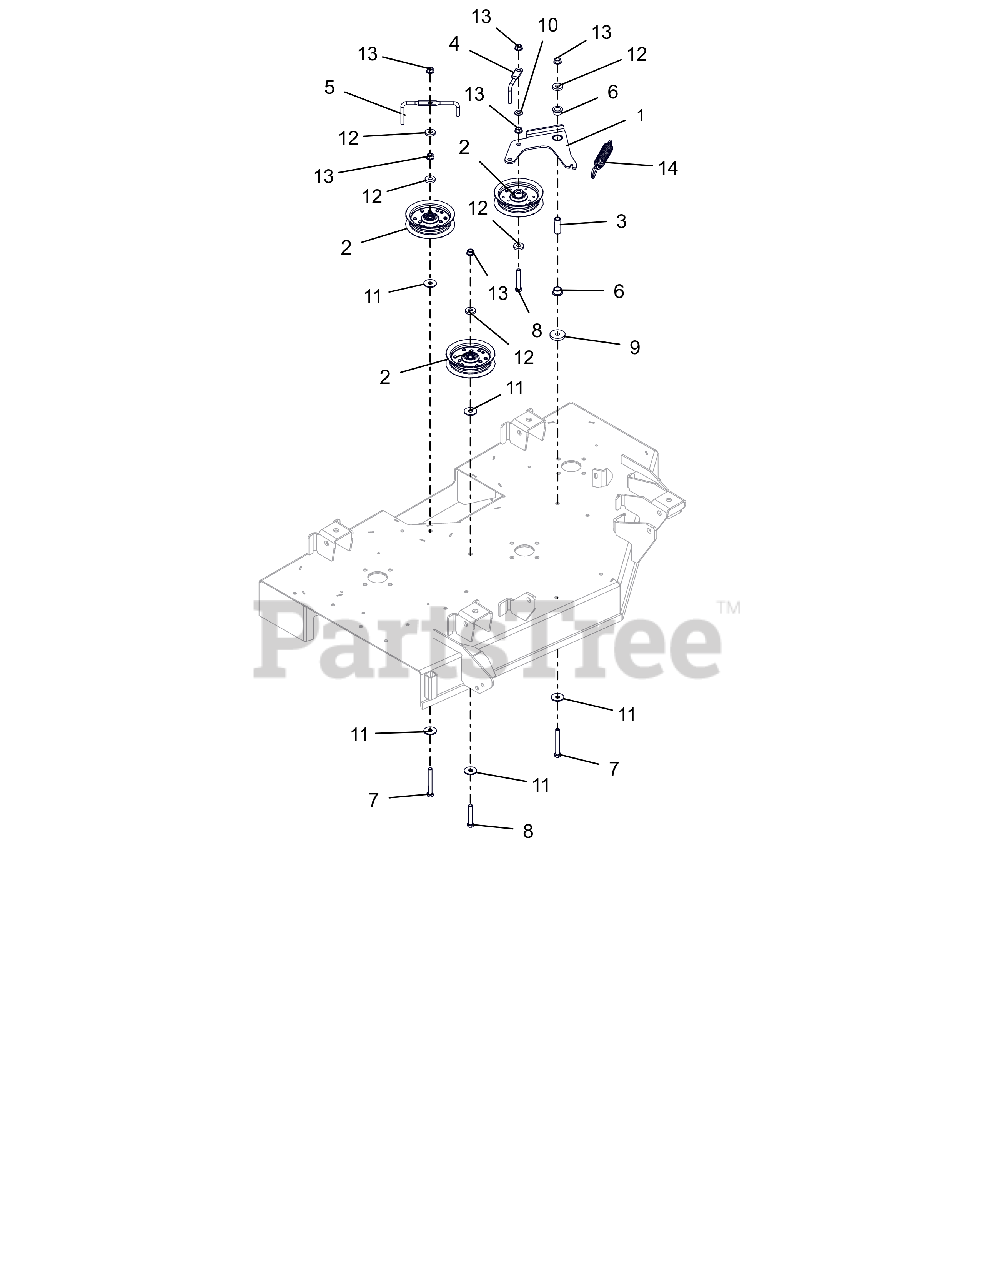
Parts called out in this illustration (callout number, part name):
1	WLDMT, IDLER ARM-42"
2	ASM, IDLER 4"
3	SPACER, .375IDX.625ODX1.66 PM
4	WIREFORM, BELT FINGER
5	WIREFORM, BELT FINGER
6	BSHG-FLG, .625X.750X.500X1.00
7	BLT-HEX .38-16X3.00 GR5 FTH YZ
8	@BLT-HEX .38-16X2.25 GR5 YWZC
9	WSHR,FLT STL.406X1.50X.245YWZC
10	WSHR, FLT .406X.812X.065 RAW
11	WSHR FL STL .406X1.25X.10ZC120
12	WSHR-FL-STL .406X1.00X.188 YWZ
13	NUT-LK-TOP-FLG .38-16 ZC120
14	SG-TENS .135X.98X6.0 WLD 62
